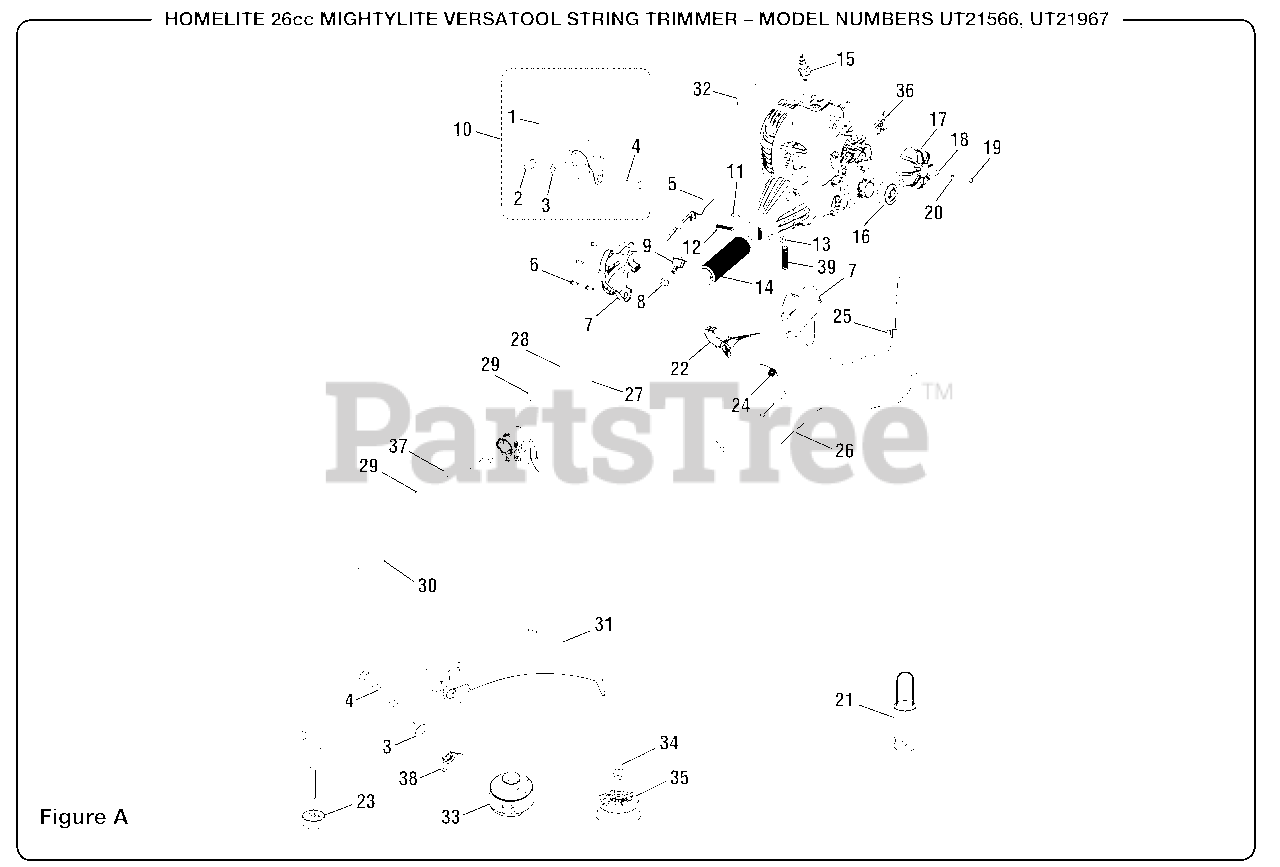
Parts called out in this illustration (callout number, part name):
2	Wing Nut (1/4-20)
4	Bolt (1/4-20 x 40 mm)
5	Throttle Lock
6	Screw (M4 x 20 mm)
7	Housing Assembly
8	Shoulder Strap Hook
9	Switch
10	Front Handle Assembly
11	Screw (8-16 x 5/16 in.)
12	Bolt (M6 x 20 mm)
13	Hex Nut (M6)
14	Rear Handle
15	Spark Plug
17	Choke Dial Cover
19	Hex Nut (M4)
20	Wavy Washer
21	Hanger Cap
22	Throttle Trigger
23	Spool Retainer
24	Torsion Spring
25	Throttle Cable
27	Upper Boom Assembly
28	Starting Label
29	Warning Label
30	Lower Boom Assembly
31	Grass Deflector
32	Choke Label
33	Complete String Head (.080 in.)
34	Compression Spring
35	Spool and String (.080 in.)
36	Logo Label
37	Expand-It Label
38	Wing Nut (1/4-20)
39	Compression Spring
